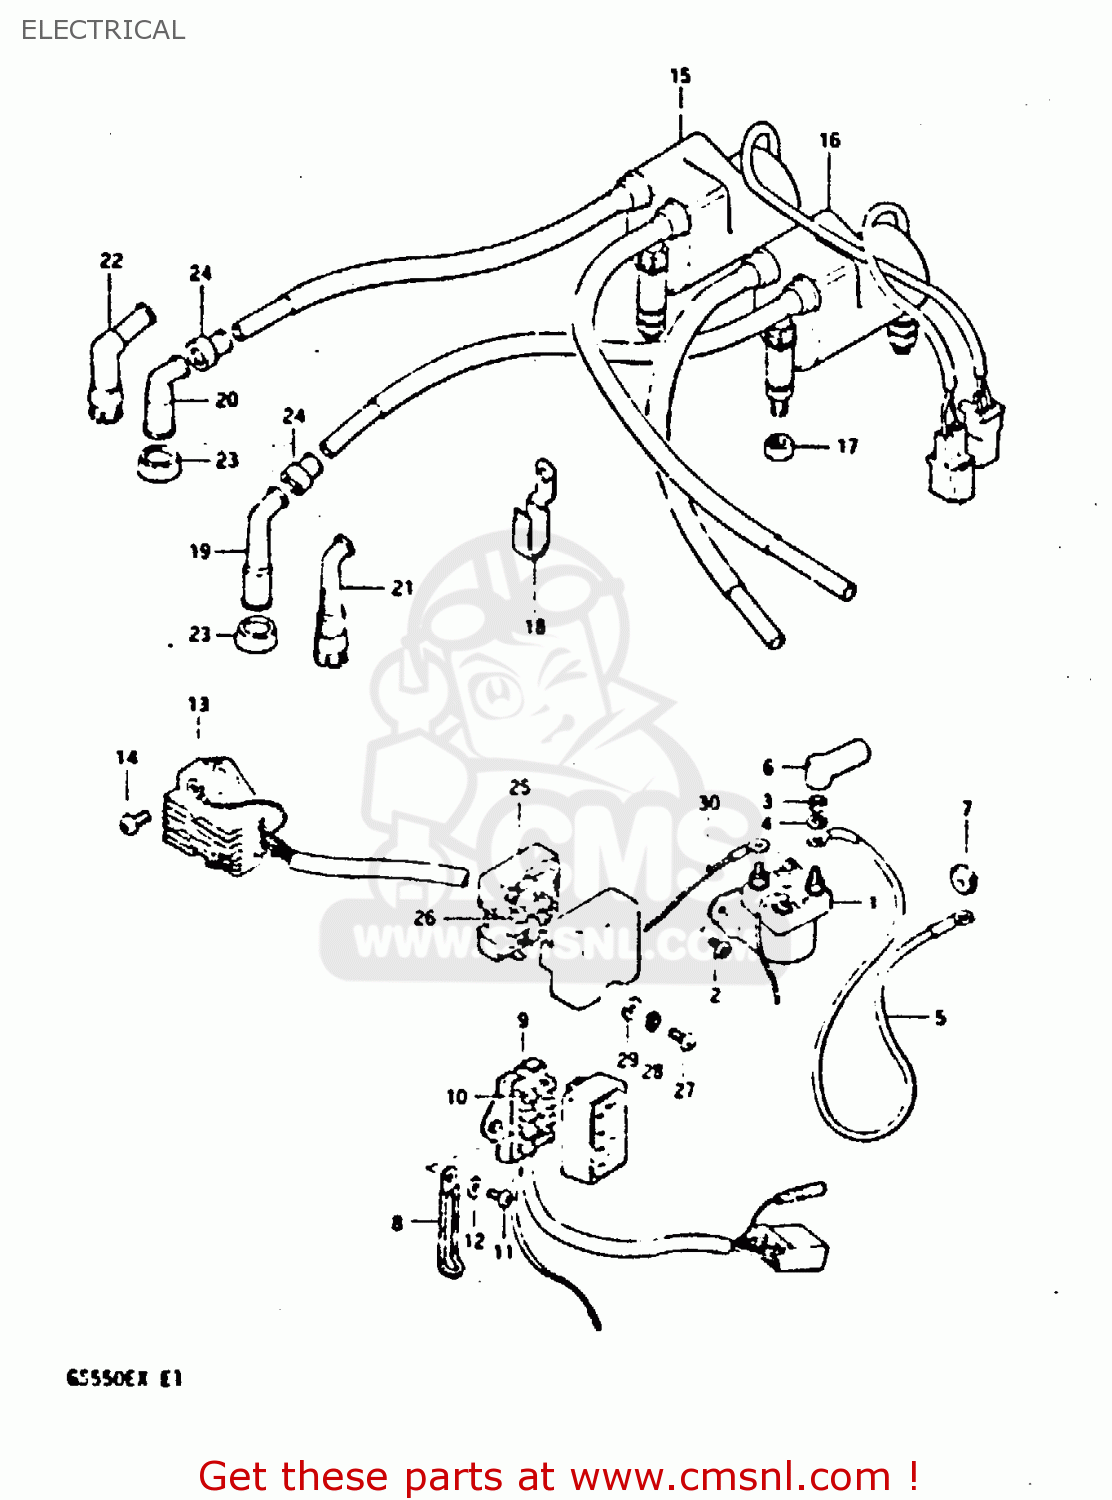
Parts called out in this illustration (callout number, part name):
1	RELAY ASSY,STARTING MOTOR
2	SCREW
3	NUT 6MM
4	LOCK WASHER
5	WIRE,STARTER MOTOR LEAD
6	CAP,STARTER RELAY
7	GROMMET,STARTER CABLE
8	CLAMP
9	BOX ASSEMBLY,FUSE
10	FUSE(15A)
11	SCREW 6X12
12	WASHER
13	RECTIFIER ASSEMBLY
14	SCREW
15	COIL ASSEMBLY,IGNITION
16	COIL ASSEMBLY,IGNITION
17	NUT
18	CLAMP
21	CAP,SPARK PLUG
22	CAP, SPARK PLUG (S)
24	SEAL,SPARK PLU
25	TERMINAL ASSEMBLY,POWER SO
26	FUSE(10A)
27	SCREW
28	LOCK WASHER
29	WASHER
30	WIRE
